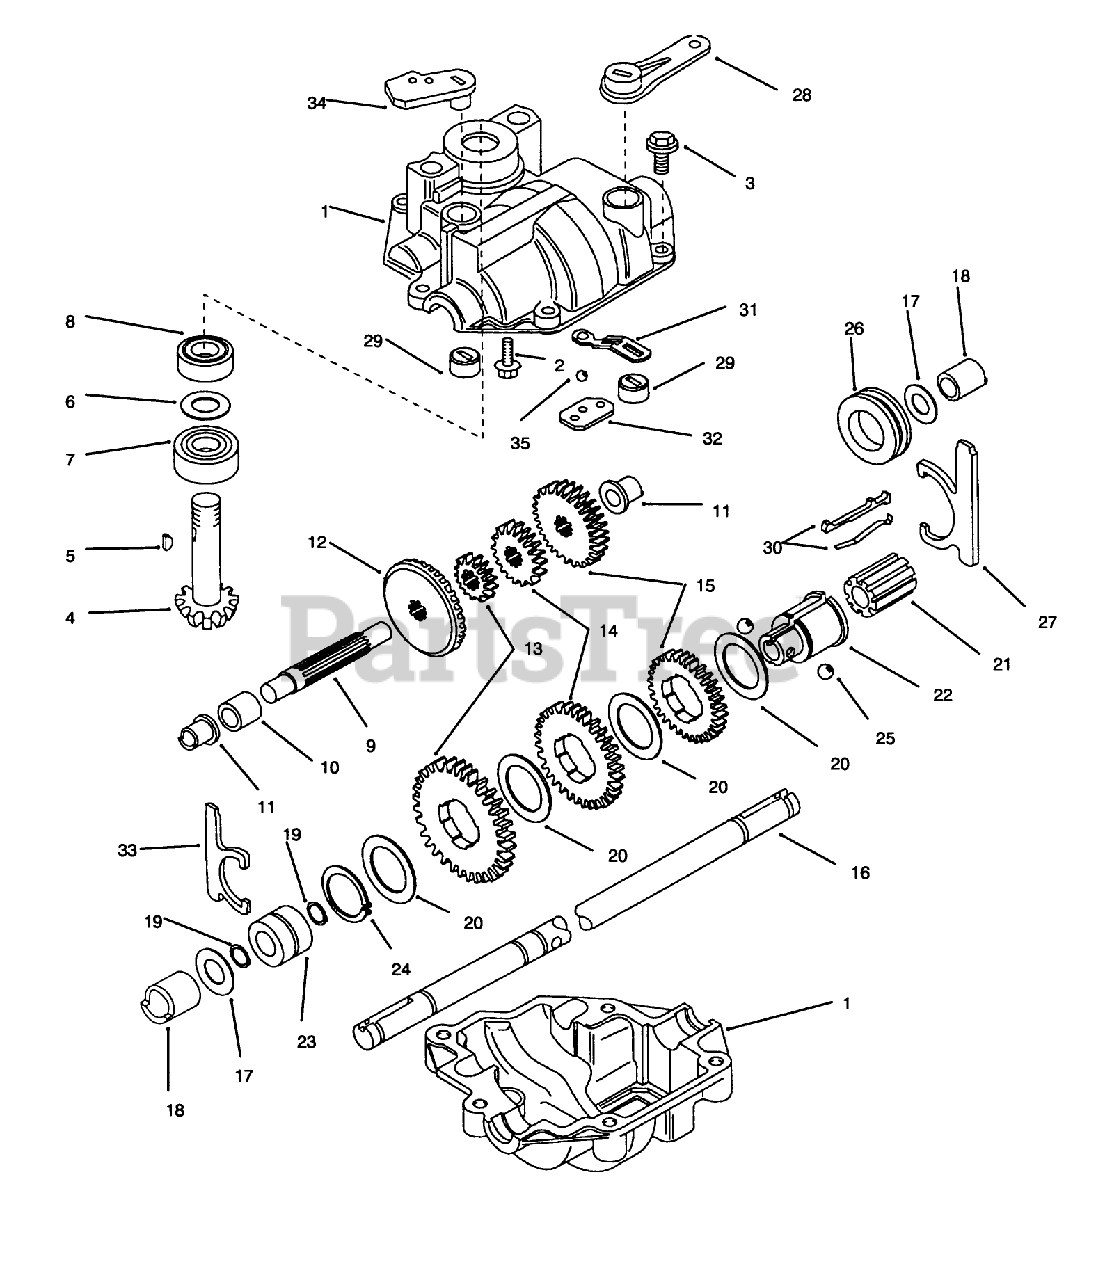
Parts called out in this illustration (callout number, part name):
5	KEY GALGER
7	BEARING
8	BEARING
12	GEAR-RING
22	COLLAR-SHFT
34	ARM - CLUTCH
